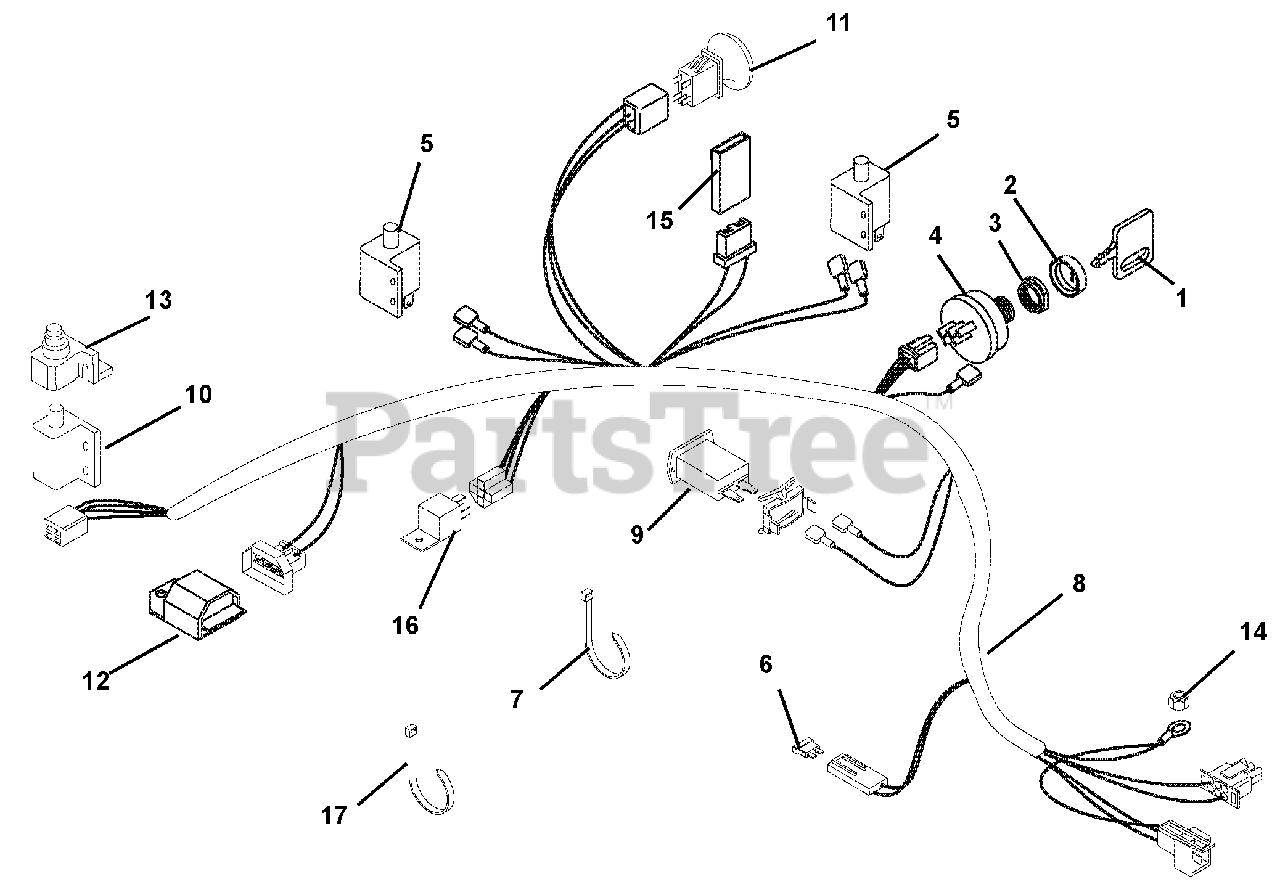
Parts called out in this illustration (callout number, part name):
1	Key, with Cap
2	Cap, Ignition Switch
3	Nut, Panel .562-24
4	Key Switch
5	Switch, Double Pole N.O./N.O.
6	Fuse, 25 AMP
7	Tie Wrap, Black
8	Wire Harness, Hydro Recoil-Pro Steer
9	Hour Meter, Quartz
10	Switch, Interlock
11	Switch, PTO- NMIR
12	Module, Interlock Recoil
13	Boot, Rubber
14	Nut, Locking-Top-Flange .31-18
15	Diode, Connector Shell
16	Relay
17	Tie Wrap
